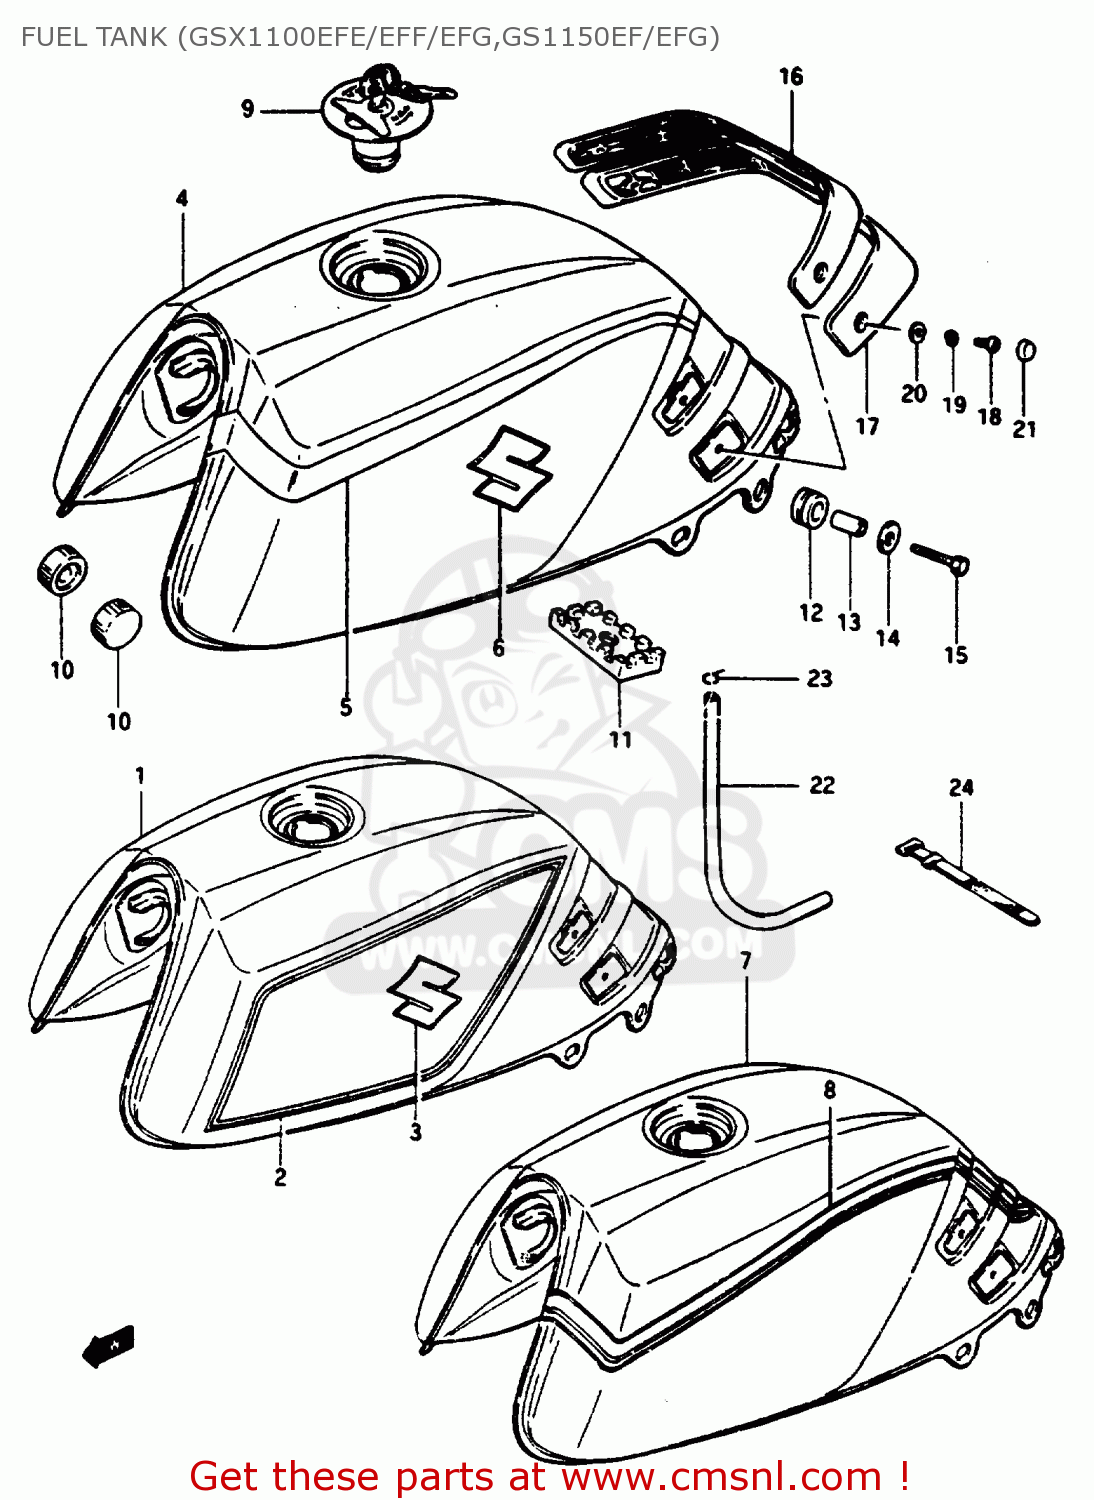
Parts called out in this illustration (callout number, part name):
1	TANK ASSY, FUEL
2	TAPE SET, FUEL TANK
3	EMBLEM
4	TANK ASSY, FUEL
5	TAPE SET,FUEL TANK
6	EMBLEM
7	TANK ASSY, FUEL
8	TAPE SET, FUEL TANK
9	CAP ASSY,FUEL TANK
10	CUSHION
11	CUSHION,FUEL TANK CTR
12	CUSHION
13	SPACER (6.4X9X20)
14	WASHER (6.5X29X1.6)
15	BOLT 6X30
16	KNEE GRIP,FUEL TANK,UPPER
17	GRIP,FUEL TANK KNEE LWR
18	SCREW
19	LOCK WASHER
20	WASHER
21	CAP,KNEE GRIP
22	HOSE,FUEL
23	CLIP
24	CLAMP(L:187)
